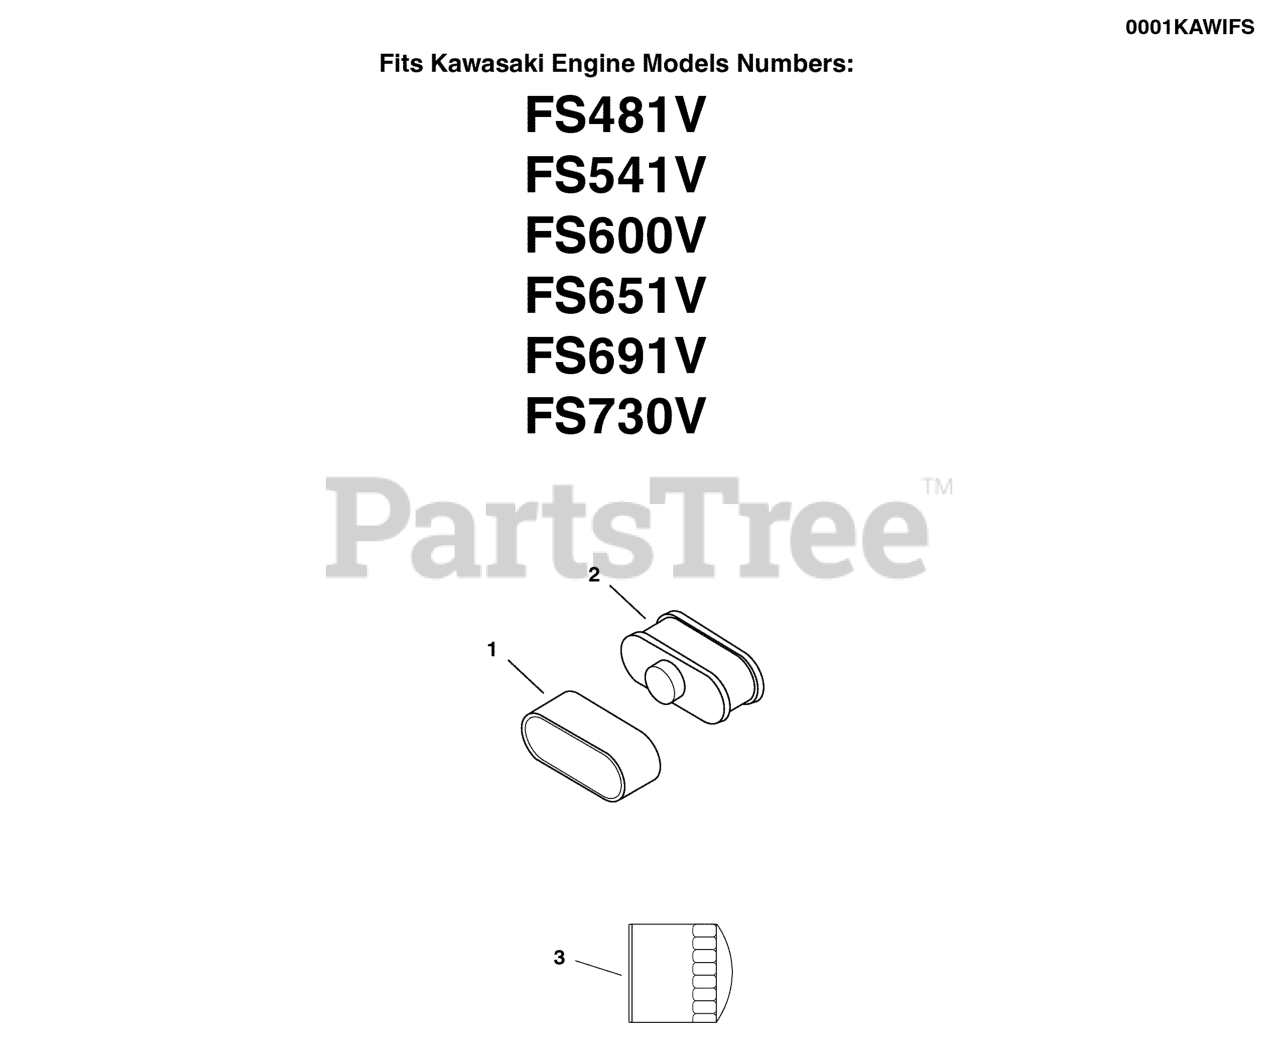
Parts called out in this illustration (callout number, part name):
1	FILTER,AIR,OUTER,KAWA FS481V THRU FS730V (11013-7046)
2	FILTER,AIR,INNER,KAWA FS481V THRU FS730V (11013-7049)
3	FILTER,OIL,KAWA FS,FX,FR 603 & 726CC ENG (49065-7007)
